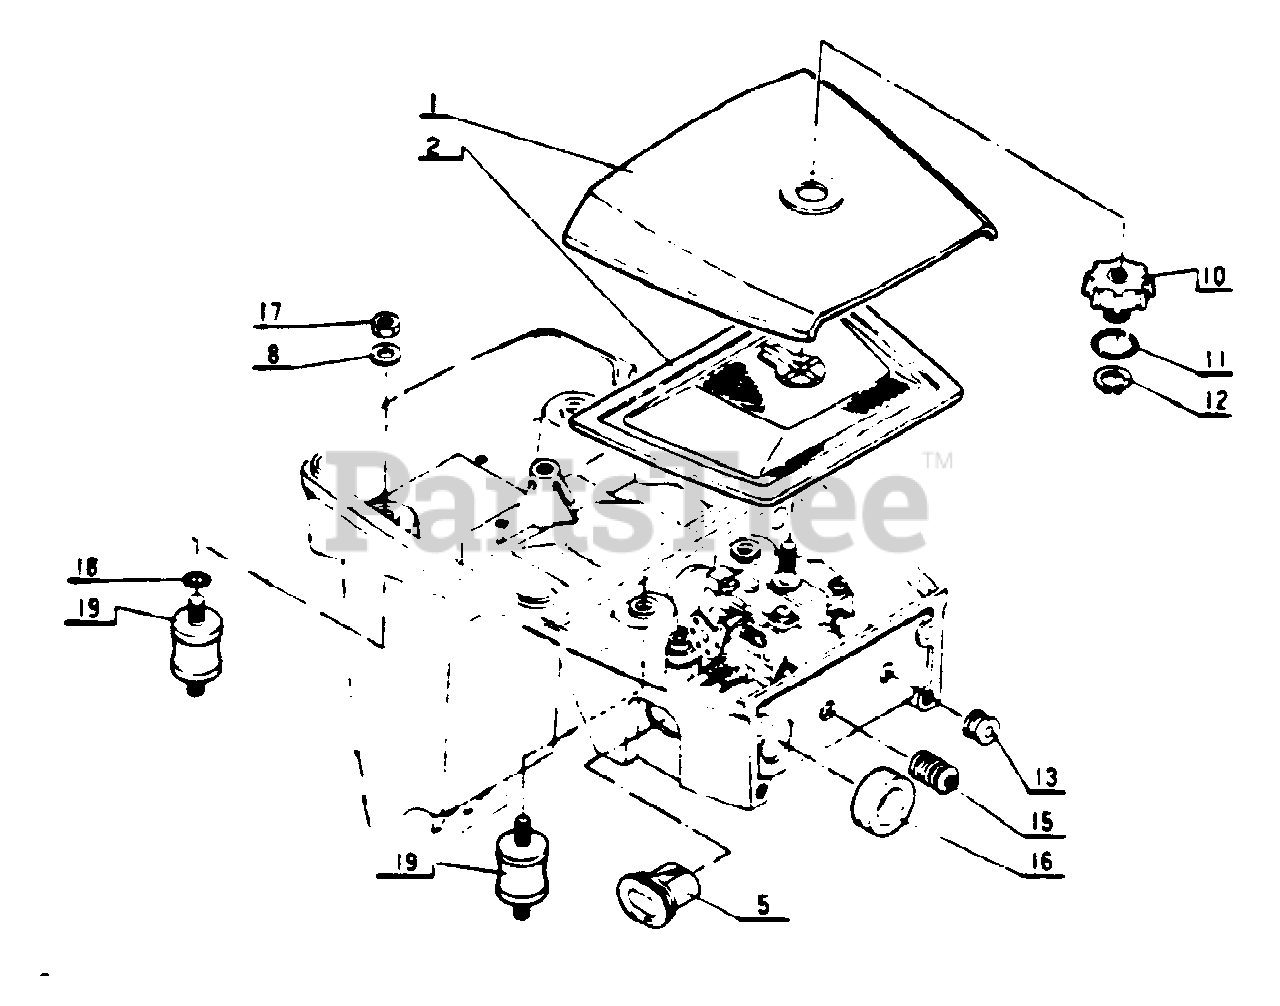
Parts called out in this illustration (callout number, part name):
1	COVER, AIR FILTER
2	FILTER, AIR
8	WASHER - 6
10	THUMBNUT
11	O-RING
12	RING, RETAINING
16	SEAL, DUST
17	LOCKNUT - 6
18	O-RING
